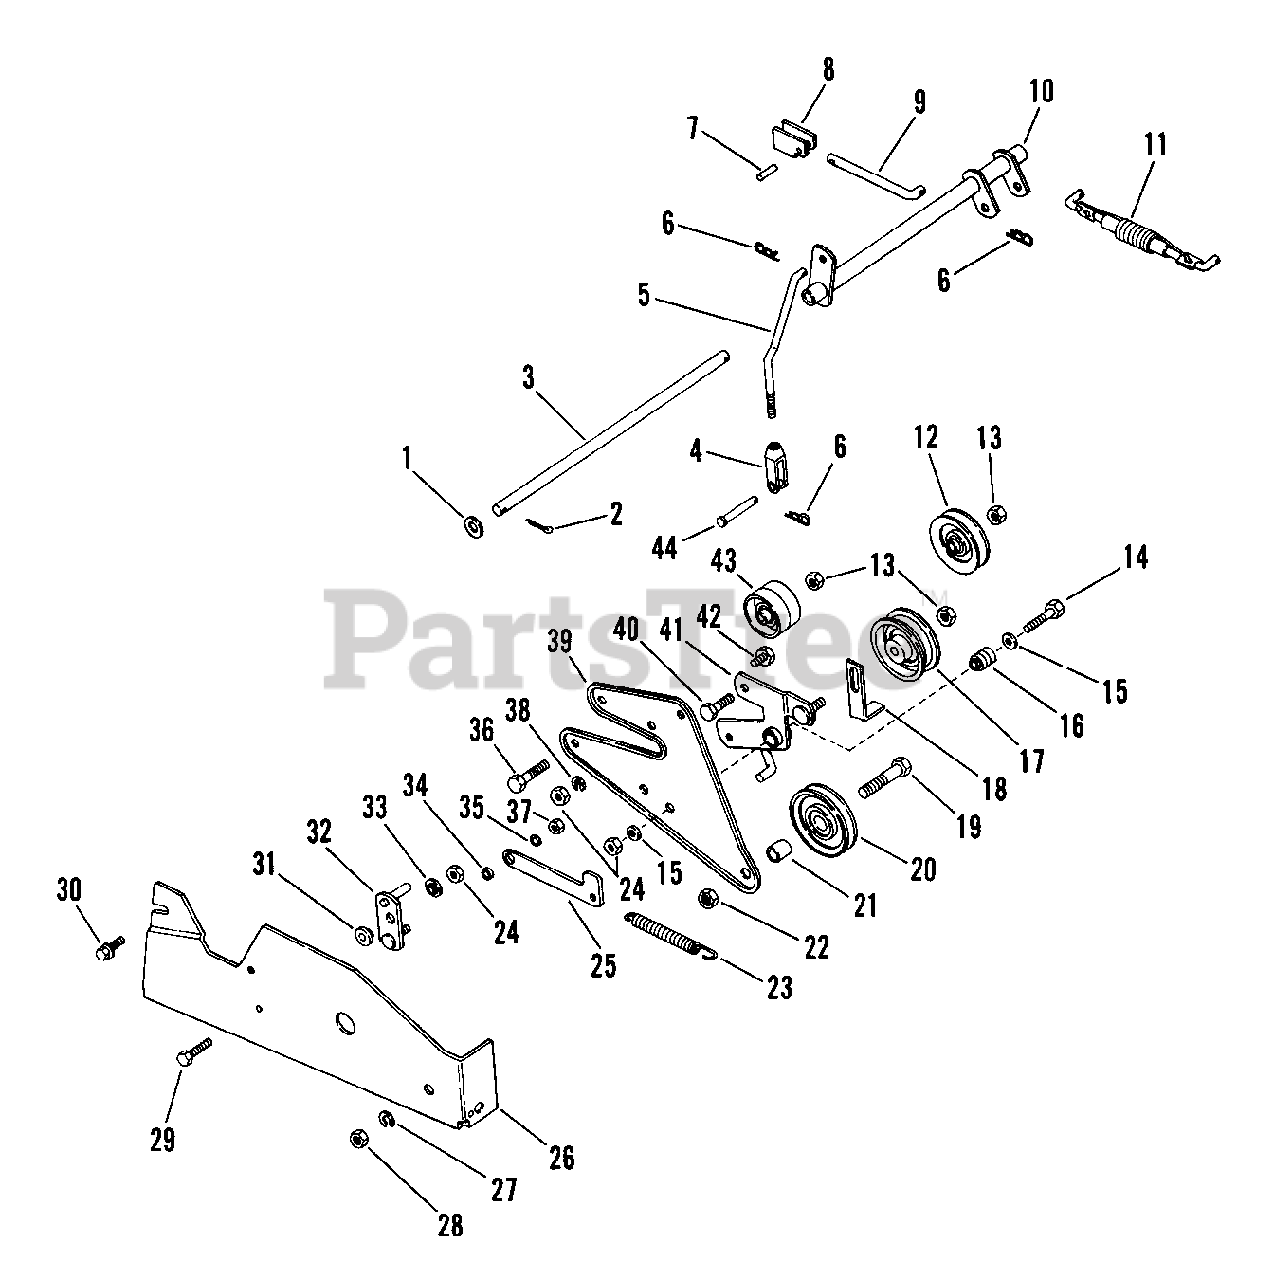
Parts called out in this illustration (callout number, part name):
1	WSHR-FL-STL .531X1.062X.095 PL
2	PIN-COTR .12X1.0 PL
3	PIVOT SHAFT
4	YOKE
6	PIN-HAIR INT .08X.18X1.18
7	PIN-ROLL .156X1.00
10	CLUTCH PIVOT
11	SPRING ASSEMBLY
12	IDLER-V 3.06 X .38
13	NUT-LK-JAM-CTR .375-16 PL
14	BLT-HEX .31-18X1.75 GR5
15	WSHR-FL-STL .328X1.0X.094
17	IDLER-FLAT 2.75 X .38 DAYCO
18	BELT FINGER
19	BLT-HEX .50-13X2.50 PL GR2 FTH
20	IDLER-V 3.50 X .50 CAPITOL
21	HUB, .50 X .75 X .84
22	NUT-LK-CTR .50-13
23	SG-TENS .062X.56X8.0 WLD 11
24	NUT-LK .312-18 GR A PL
26	BELT GUARD & BRAKE
27	WSHR-LK .500X.151 HVY PL
28	NUT-JAM .50-13 PL
29	BLT-HEX .31-18X1.25 PL GR5
30	SCREW - FLG WIZ LOCK HH PL
31	SPACER -FLANGED .325X.498X.318
32	BRAKE ARM
33	BSHG, FLG .325X.499X.26X.88
34	SPACER BUSHING .5 X .32 X .163
35	WSHR-FL-STL.344X.688X.065PL
36	BLT-HEX .38-16X1.75 PL GR5
37	NUT-HEX .375-16
38	WSHR-LK .375X.094 MED PL
39	DRIVE MOUNT
40	BLT-HEX .38-16X1.25 PL GR5
41	CLUTCH PIVOT WELDMENT
42	BLT-HEX .38-16X.75 PL GR5
43	IDLER-FLAT 2.25 X .38
44	CLEVIS PIN
